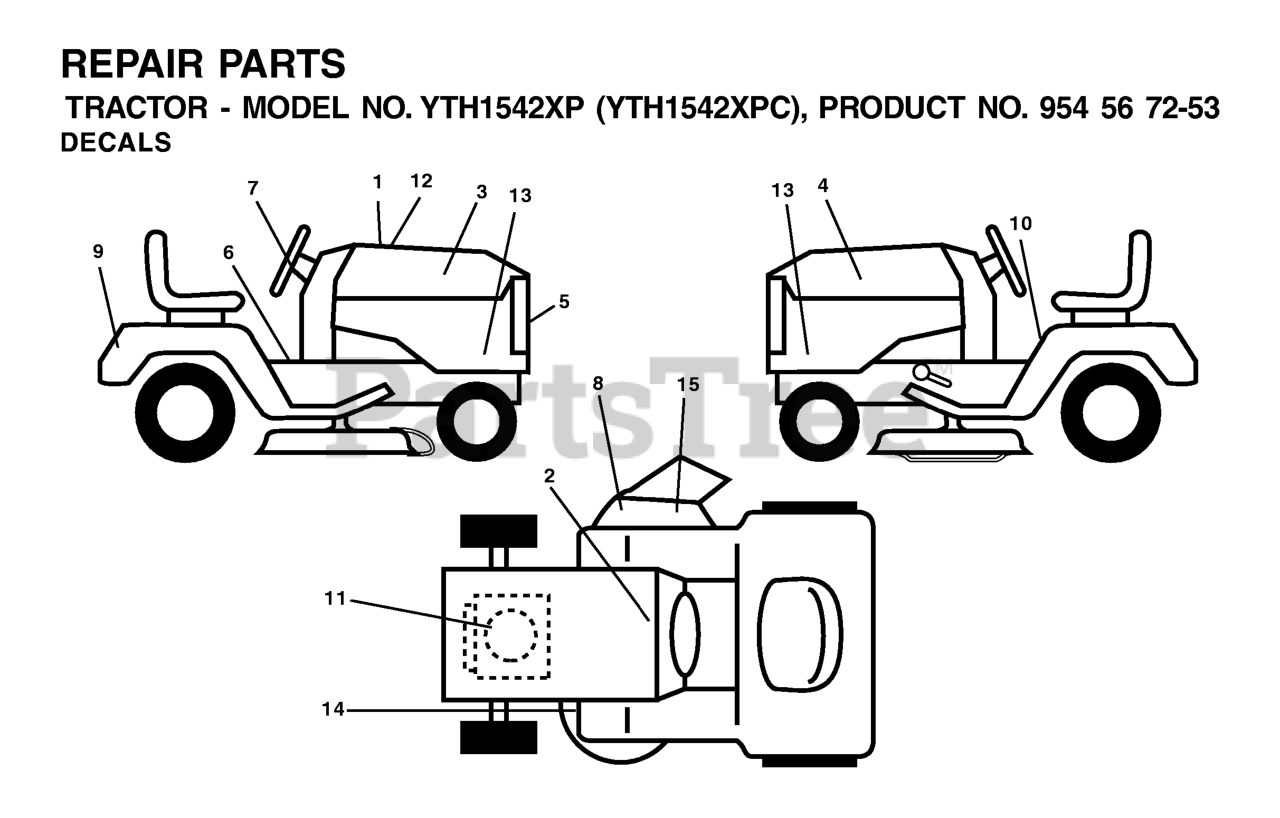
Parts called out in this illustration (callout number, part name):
1	DECAL HOOD CUST. RESP.
2	DECAL BTRY SYMBOLS
5	DECAL.GRILLE.HUSQ
7	DECAL.WHEEL.STEERING.HUSQ.PERM
8	DECAL.WARN.KEEP.HAND.AWAY
9	DECAL, FENDER
10	DECAL FENDER DANGER
13	DECAL HOOD SIDES
14	DECAL V BELT SCHEMATIC
15	DECAL DECK "B" 42"
